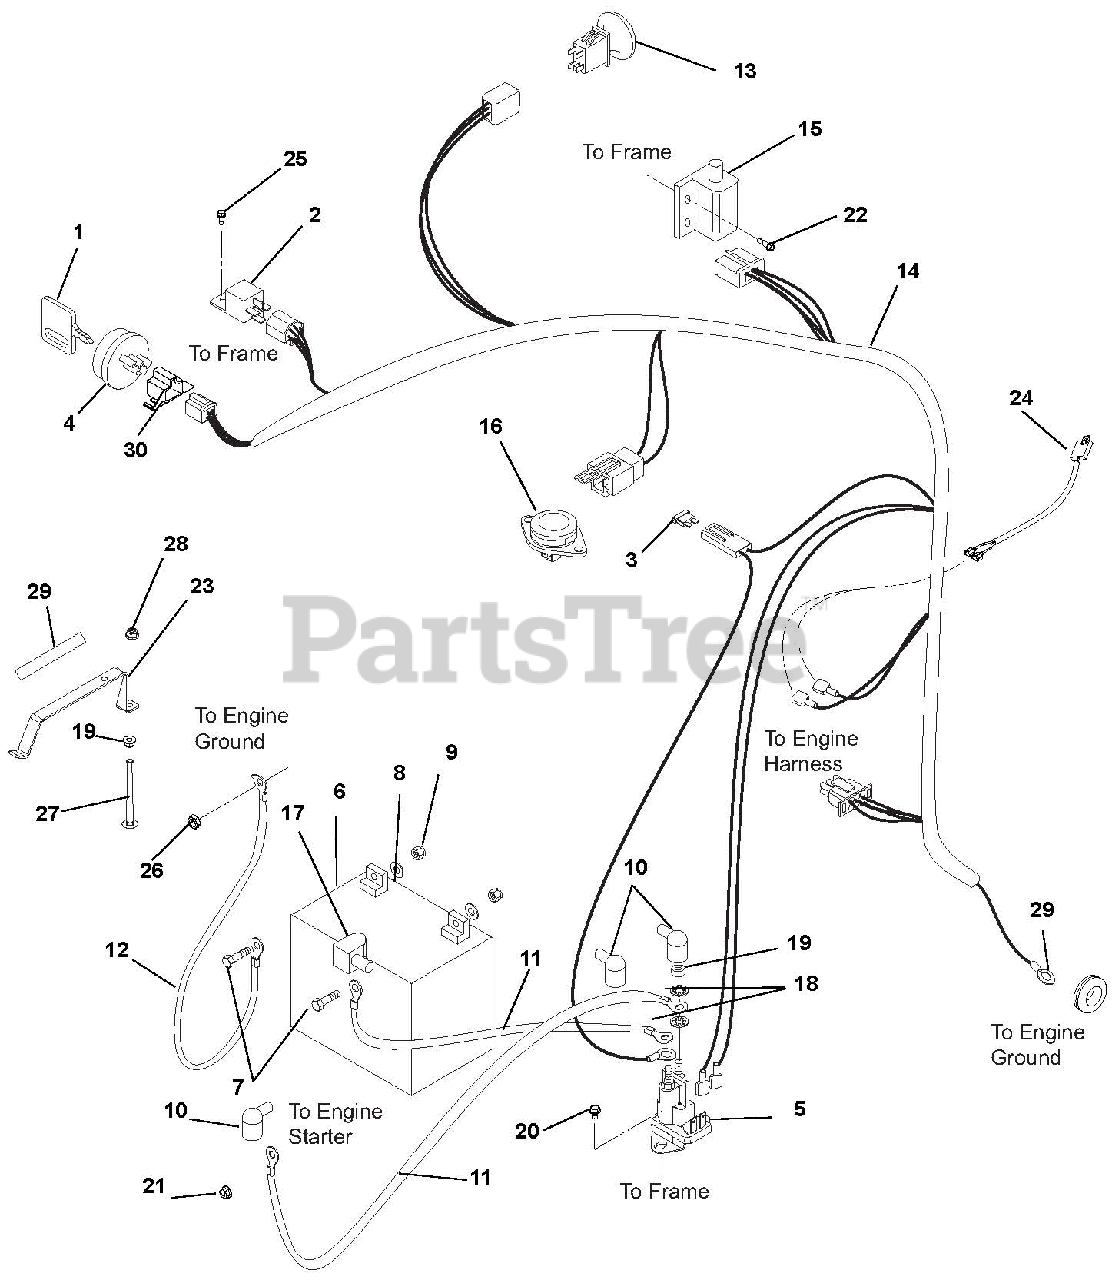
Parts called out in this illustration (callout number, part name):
1	Key
1	Key- with Cap
2	Relay
3	Fuse, 30 AMP
4	KEYSWITCH-IGNITION 3 POS
4	Key Switch
5	Solenoid
6	Battery, 12V 12A
7	Bolt, Hex .25-20 x .75
8	Washer, Flat Steel .281 x .62 x .065
9	Nut, KEPS .250-20
10	Boot, Eyelet Terminal
11	Cable, POS
12	Ground Cable
13	Switch, Clutch With Retainer
14	Harness, Wiring Zoom
15	Switch, Double Pole N.O. / N.O.
16	Switch, Snap Mounting N.O.
17	Insulator
18	Washer, Locking .31
19	Nut-Hex M6x1.0
20	Screw, Tapping .250-20 x .37 Hex Washer Head
21	Nut, Locking Top Flange .25-20
22	Screw, 12-14 x .75 HX
23	Hold Down, Battery
24	Harness, Clutch
25	Screw, Tapping 10-24 x .50 HWH TR YWZC
26	Nut, Locking Center Jam .375-16
27	Bolt, Round Head Square Neck .25-20 x 4.50
28	Nut, Locking Nylon Flange .25-20
29	Cable Tie
30	Wire Harness, Key Switch ADAPT
